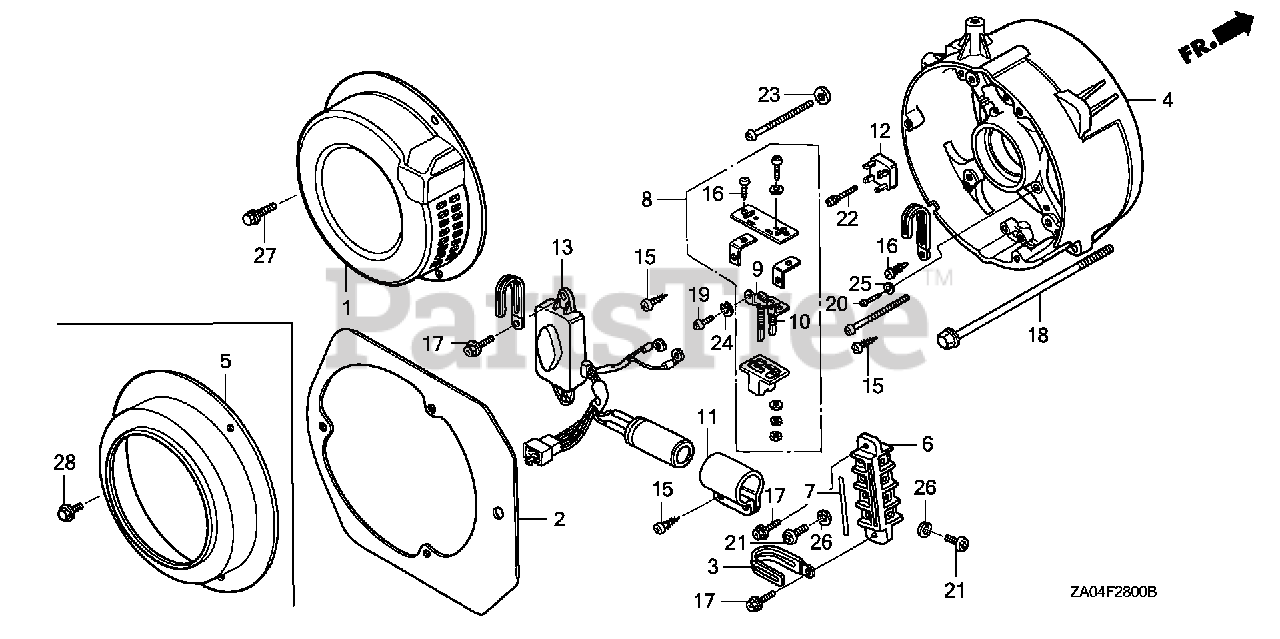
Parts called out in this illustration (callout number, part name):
3	CLAMP B, WIRE
4	HOUSING, RR. *NH116M* (URBAN SILVER METALLIC) (NOT AVAILABLE)
5	COVER, GENERATOR END
6	TERMINAL, A.C. OUT
7	MARK, A.C. OUTPUT
8	HOLDER ASSY., BRUSH
11	HOLDER, CONDENSER
12	STACK, DIODE
13	REGULATOR ASSY., AUTOMATIC VOLTAGE
15	SCREW, TAPPING (5X12)
16	SCREW, TAPPING (5X14)
17	SCREW, TAPPING (5X14)
18	BOLT, FLANGE (8X220)
19	SCREW, PAN (4X8)
20	SCREW, PAN (5X12)
21	SCREW, PAN (6X8)
22	SCREW-WASHER (4X20)
24	WASHER, SPRING (4MM)
25	WASHER, SPRING (5MM)
26	WASHER, SPRING (6MM)
28	BOLT, FLANGE (6X10)
